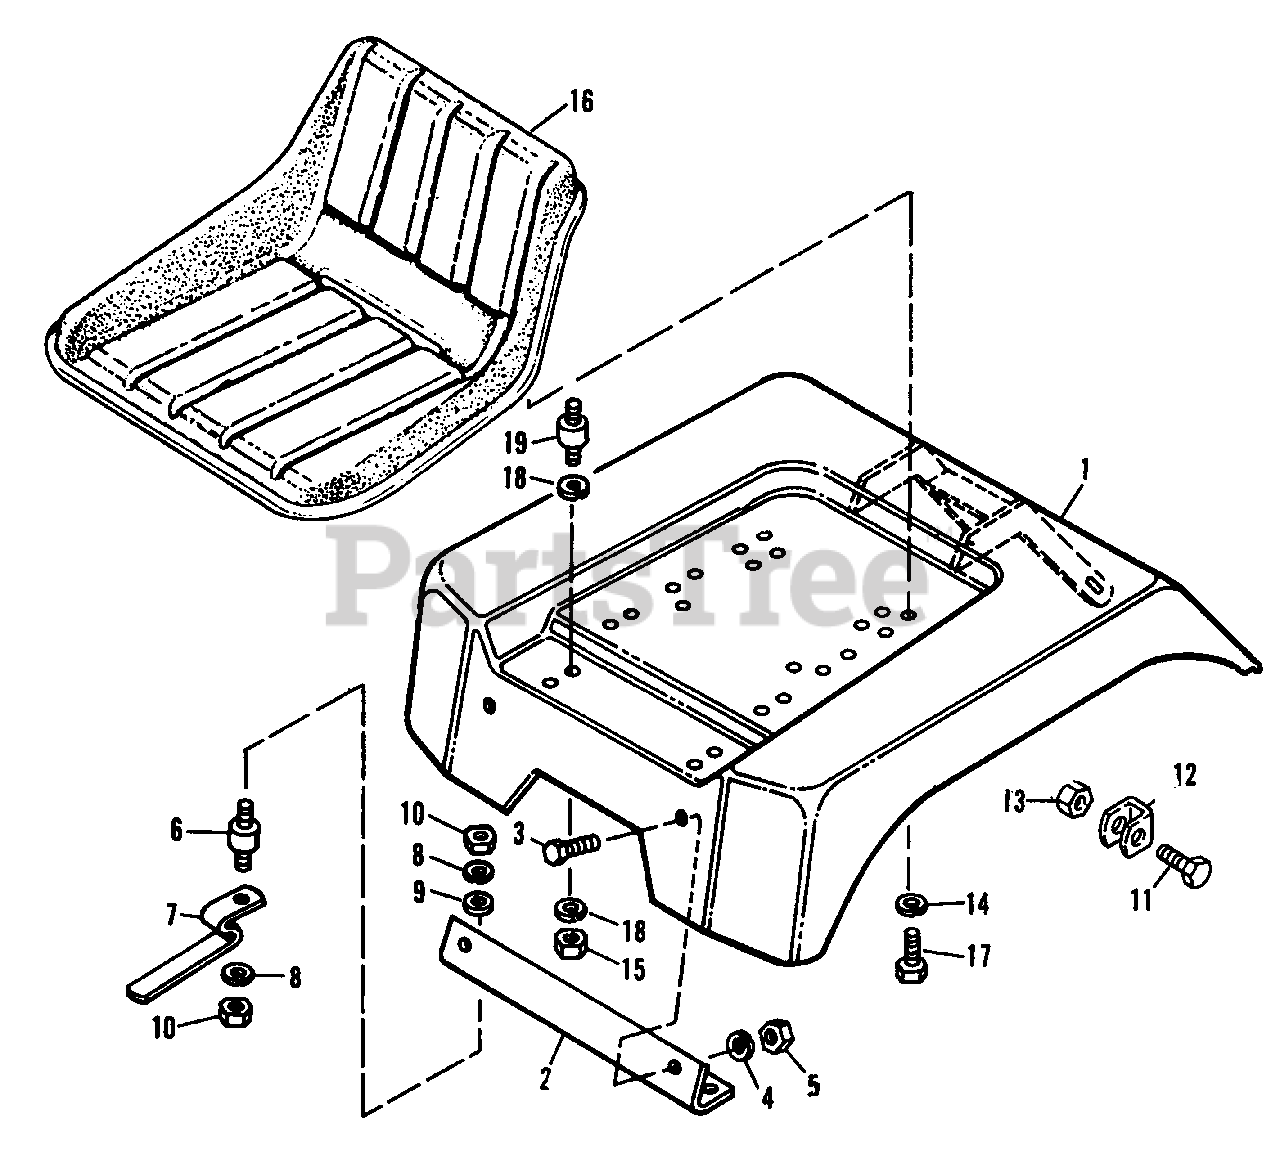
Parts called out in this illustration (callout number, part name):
1	DECK ASSEMBLY, Seat
2	BRACKET, Frt. Seat Deck
3	CAPSCREW, Hex, 5/16" 18 x 5/8" lg.
4	LOCKWASHER, 5/16"
5	NUT, Hex, Full, 5/16"-18
6	CONNECTOR, Cushion, Frt.
7	CLIP, Seat Deck Latch
8	LOCKWASHER, 5/16"
9	WASHER, Plain, 1/4"
10	NUT, Hex, Full, 5/16"-18
11	CAPSCREW, Hex, 3/8"-16 x 1-1/4" lg.
12	STOP, Seat Deck
13	NUT, Hex, Full, Lock, 3/8"-16
14	LOCKWASHER, 5/16"
15	NUT, Hex, Full, 5/16"-18
16	CONTOUR SEAT ASSEMBLY
17	CAPSCREW, Hex, 5/16-18 x 5/8" lg.
18	LOCKWASHER, 5/16"
19	CONNECTOR, Cushion
20	NUT, Hex, Full, 5/16"
